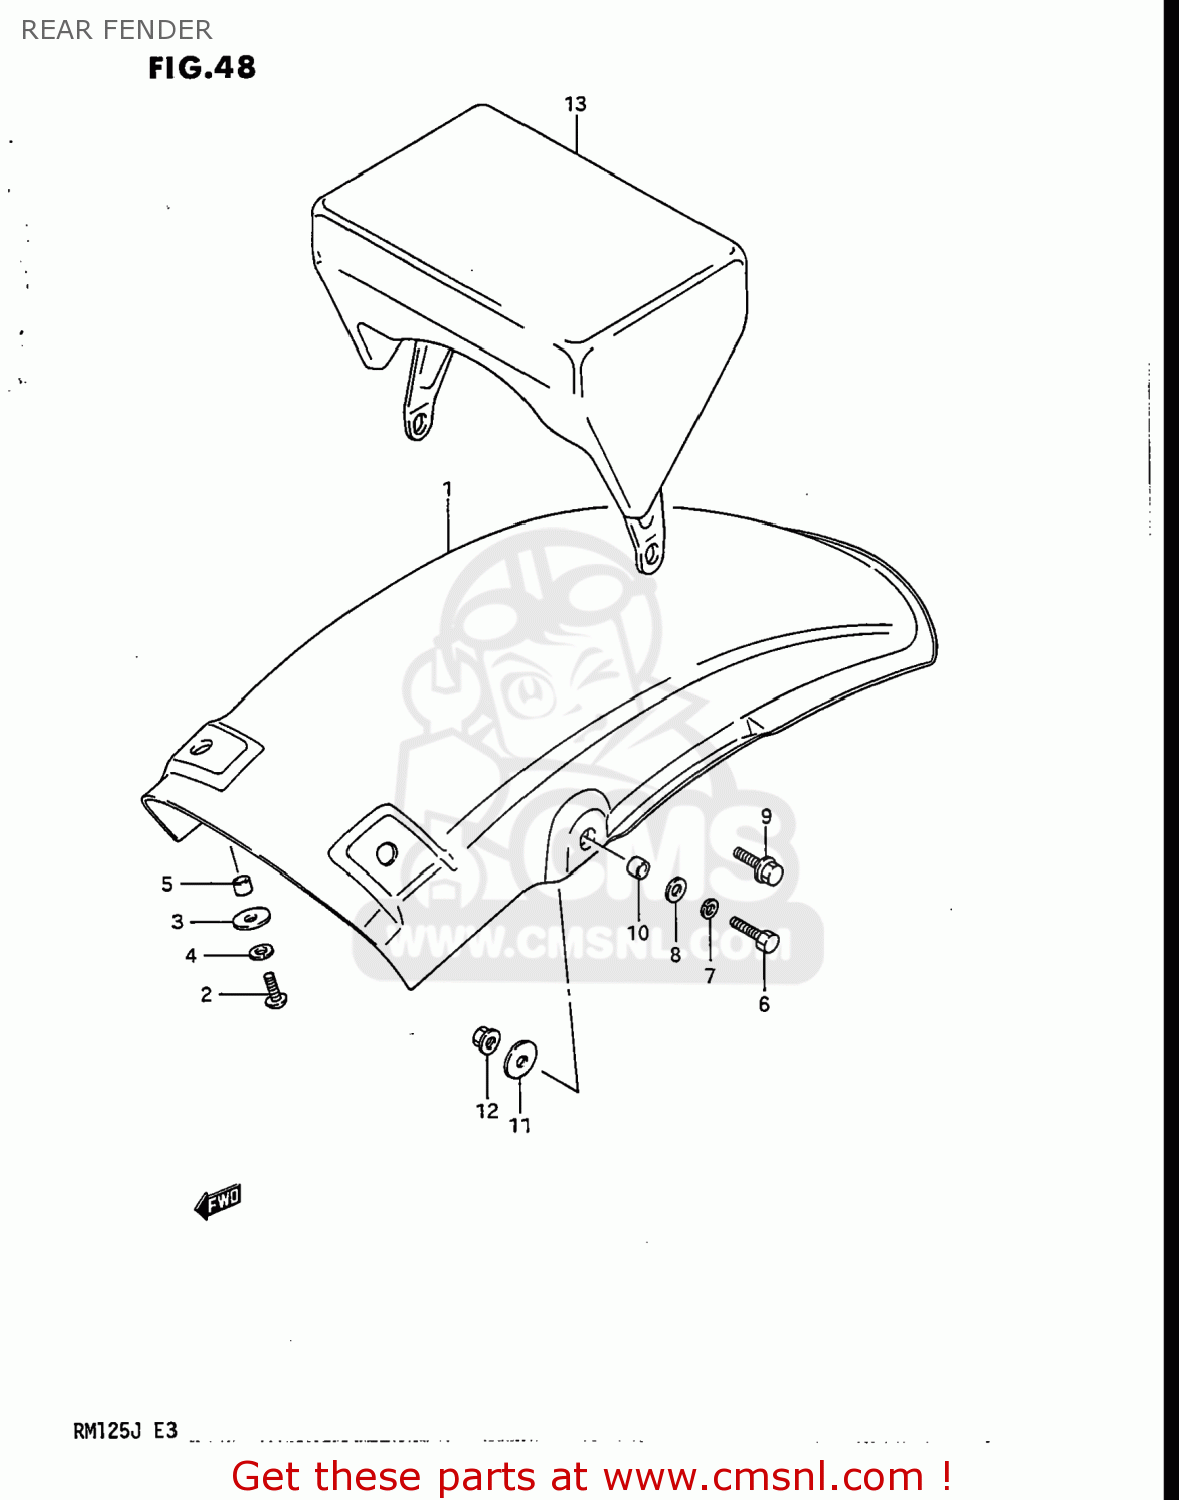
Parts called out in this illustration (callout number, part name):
1	FENDER,REAR
2	SCREW
3	WASHER
4	WASHER,LOCK
5	SPACER
6	BOLT
7	WASHER,LOCK
8	WASHER
9	BOLT 6X20
10	SPACER
11	WASHER (6.5X20X1.2)
12	NUT
13	BAG ASSEMBLY,SEAT TAIL
